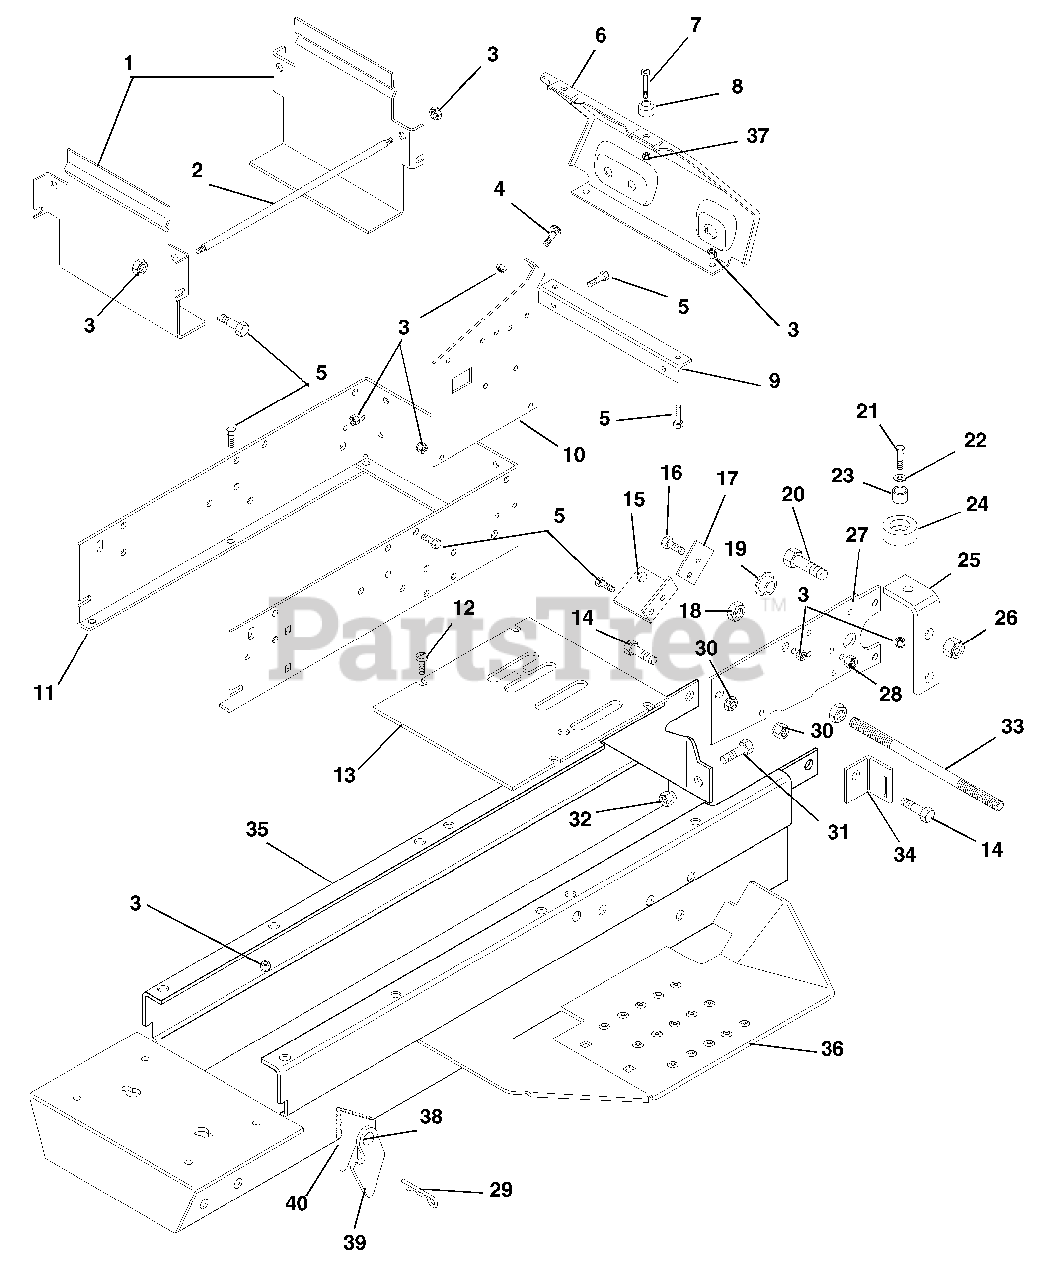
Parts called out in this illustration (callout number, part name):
1	Tank Support
2	Rod, Tank
3	Nut-Locking-Center .25-20
4	Screw-Machine .25-20 x .75
5	Bolt-Hex .25-20 x .75 Grade 5
6	Instrument Panel
7	Screw-Machine 6-32 x .75 Hex Washer Head
8	Bumper
9	Bracket, Instrument Panel
10	Bracket, Instrument Panel Left Hand
10	Bracket, Instrument Panel Right Hand
11	Support Instrument
12	Screw-Tapping .25-20 x .75 Hex Washer Head
13	Plate, Control Cover
13	Decal, G-Series Cover Plate
14	Bolt-Hex .38-16 x 1.25 Grade 5
15	Bracket, Interlock Switch
16	Bolt-Hex .31-18 x .75 Grade 5
17	Bracket, Bushing Lock
18	Nut-Hex .50-13
19	Bushing-Flange Nylon .76 x 1.00 x .58 x 1.48
20	Bolt-Hex .50-13 x 1.50 Grade 5
21	Bolt-Hex .25-20 x 1.25 Grade 5
22	Washer-Flat-Steel .31 x .73 x .065
23	Bushing-Sleeve Steel .27 x .38 x.25
24	Bumper, Seat
25	Bracket, Rear Hitch
26	Nut-Locking-Center .50-13
27	Plate, Forward-Reverse Mounting
28	Nut-Locking-Center .31-18
29	Pin-Hair-Internal .15 x 2.94
30	Nut-Locking-Center .38-16
31	Bolt-Hex .50-20 x 1.50
32	Nut-Lug .50-20
33	Rod, Frame External Brace
34	Bracket,Fender Hold-Up
35	Weldment, Frame
36	Weldment, Mower Bracket Right Hand
36	Weldment, Mower Bracket Left Hand
37	Nut-Locking-Nylon 6-32 with Insert
38	Rivet-Solid .50 x .81
39	Latch, Attachment
40	Plate,Mower Bracket
